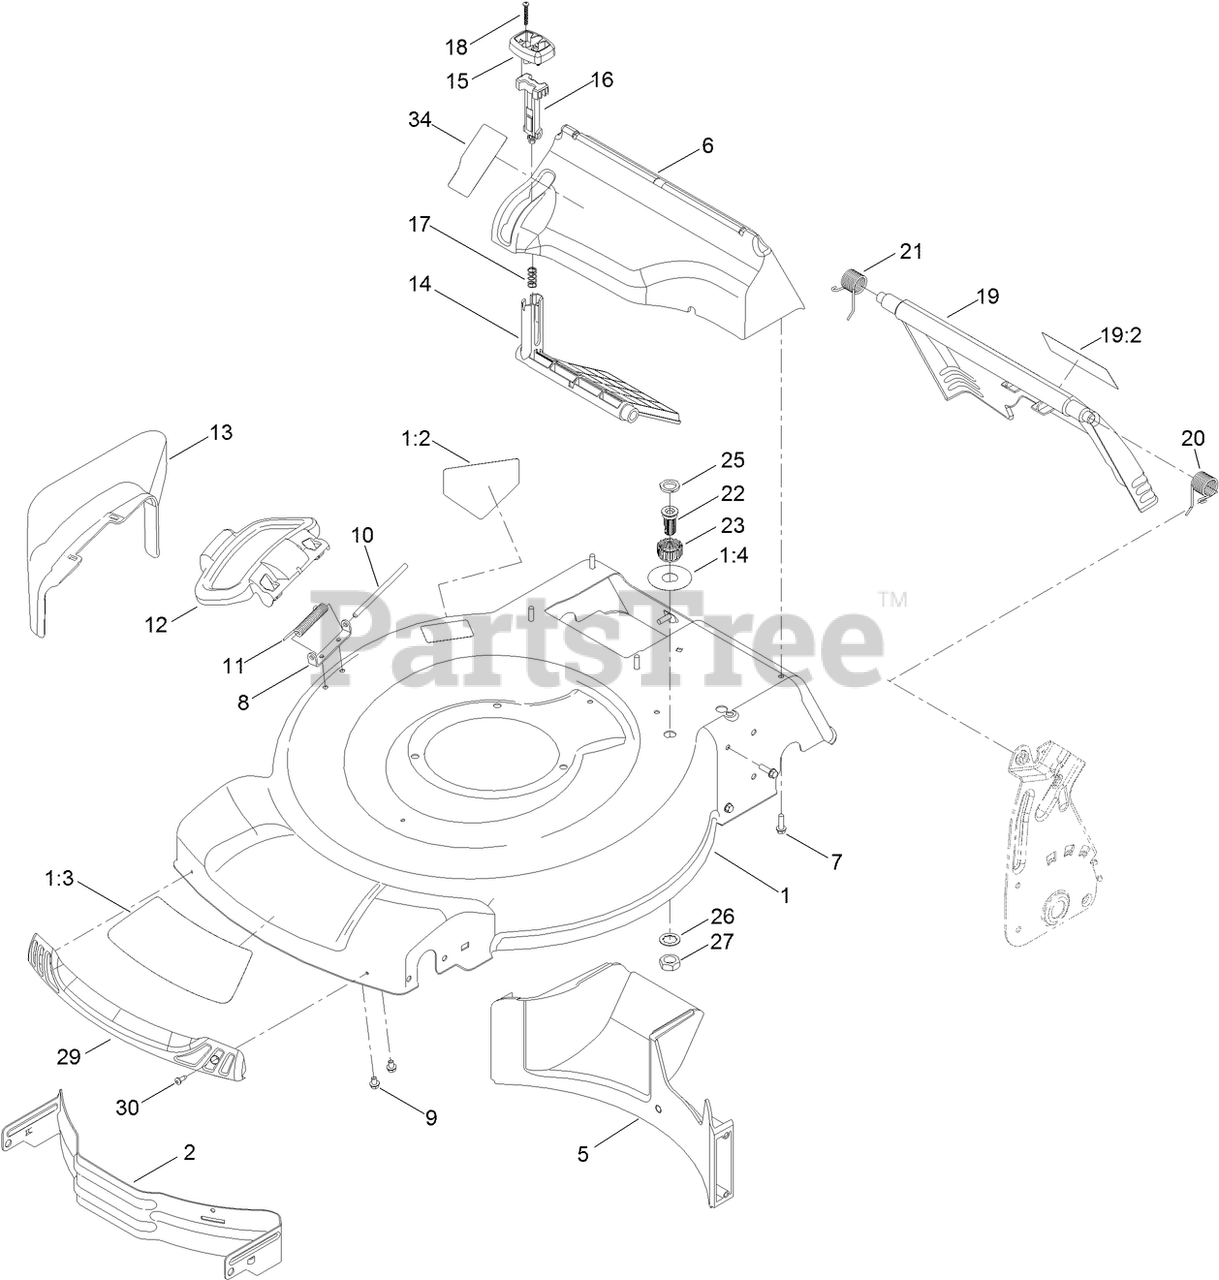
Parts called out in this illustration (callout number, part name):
1	HOUSING ASM
1:2	DECAL-DANGER
1:3	DECAL-RECYCLER
1:4	DECAL-PORT, WASHOUT
2	BAFFLE-FRONT
5	BAFFLE-REAR
6	CHUTE-RECYCLE
7	SCREW-HWH
8	BRACKET-COVER
9	SCREW-HWH
11	SPRING-TORSION
12	DEFLECTOR-SIDE
13	CHUTE-DISCHARGE, SIDE
14	DEFLECTOR-RECYCLE
15	KNOB-RECYCLE
16	LATCH-RECYCLE
17	SPRING-COMPRESSION
18	SCREW-PPH
19:2	DECAL-WARNING
20	SPRING-TORSION
21	SPRING-TORSION
22	PORT-WASHOUT
23	COUPLING-HOSE, WASHOUT PORT
25	WASHER-SEAL, WASHOUT PORT
26	WASHER-LOCK
27	NUT-JAM
29	BUMPER
30	SCREW-FORMING, THREAD
